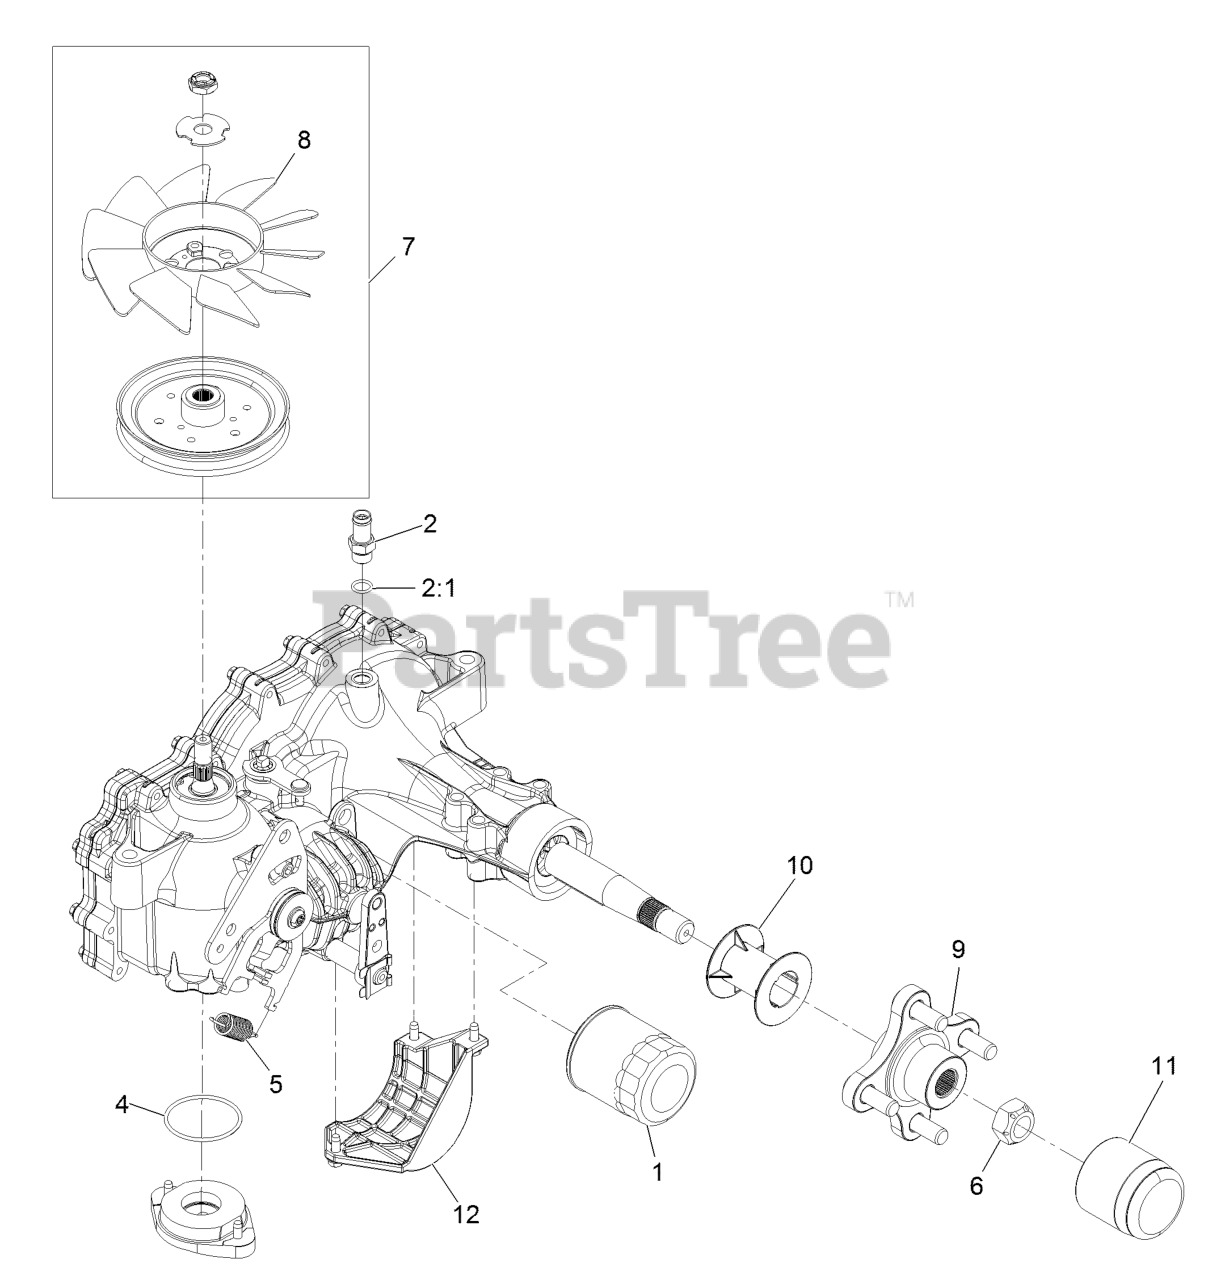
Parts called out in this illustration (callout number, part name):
1	ELEMENT-OIL FILTER, HYD
2	ADAPTER-STRAIGHT
2:1	O-RING
4	O RING-SEAL
5	SPRING-EXTENSION
6	NUT-HUB
9	HUB-OFFSET
10	TUBE-AXLE
11	CAP-AXLE, LONG
12	GUARD-FILTER, LH
